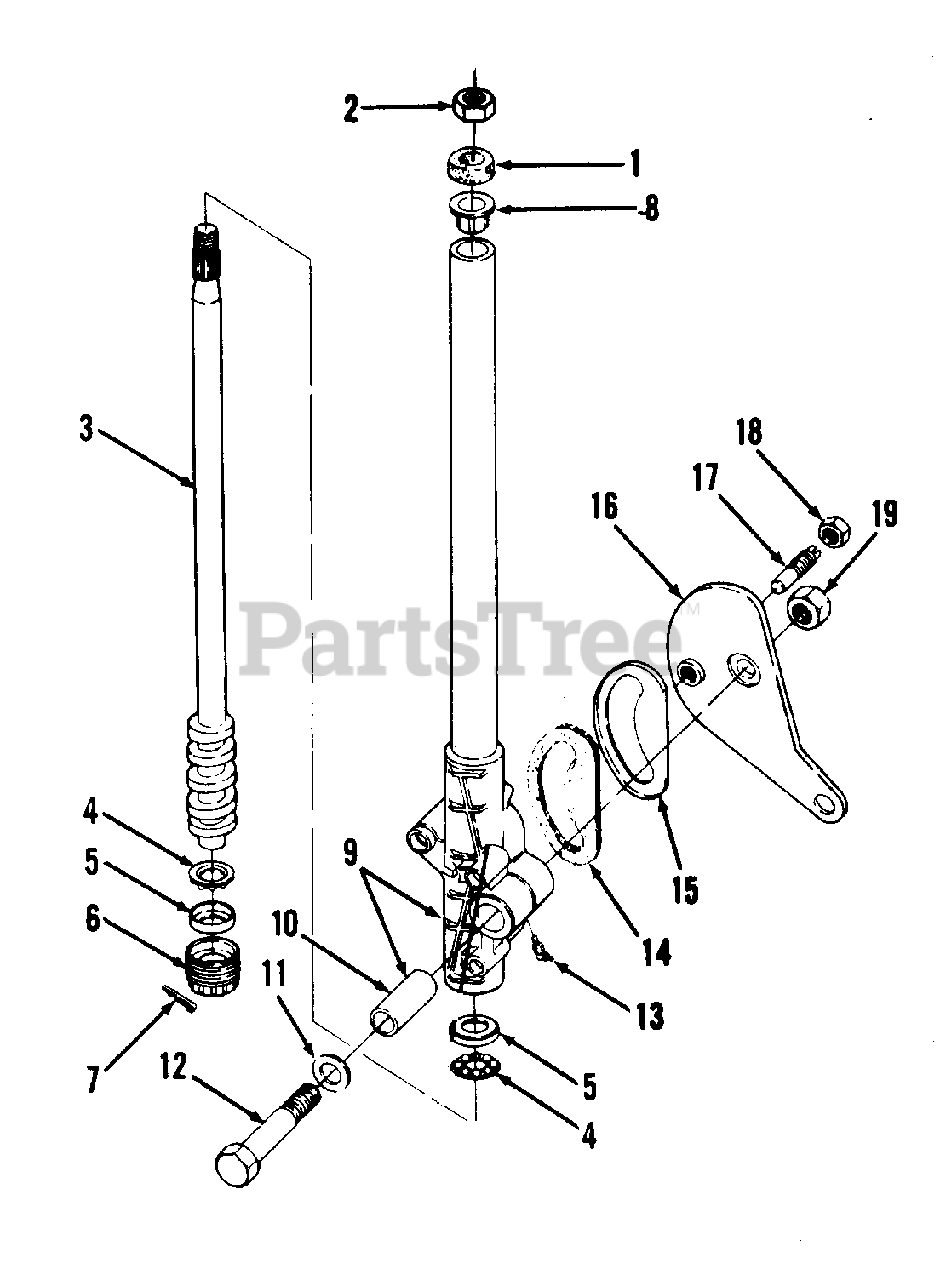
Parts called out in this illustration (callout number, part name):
1	Seal, Column
2	Nut, Hex Jam, 5/8-18
3	Shaft/Cam Assy
4	Retainer Assy, Ball
5	Cup, Bearing
6	Plug, Adjusting
7	Pin, Cotter, 1/8 Dia X .75 Lg
8	Bearing, Column
9	Housing/Tube Assy
11	Washer, Flat, .791 X 1.24 X .060 Thk
12	Shaft, Pivot
13	Fitting, Lube, 3/16 Drive Type
14	Seal, Grease
15	Retainer, Seal
16	Arm, Steering
17	Follower, Cam
18	Nut, Hex Jam, 9/16-18
19	Nut, Hex Crown Loc, 5/8-18
